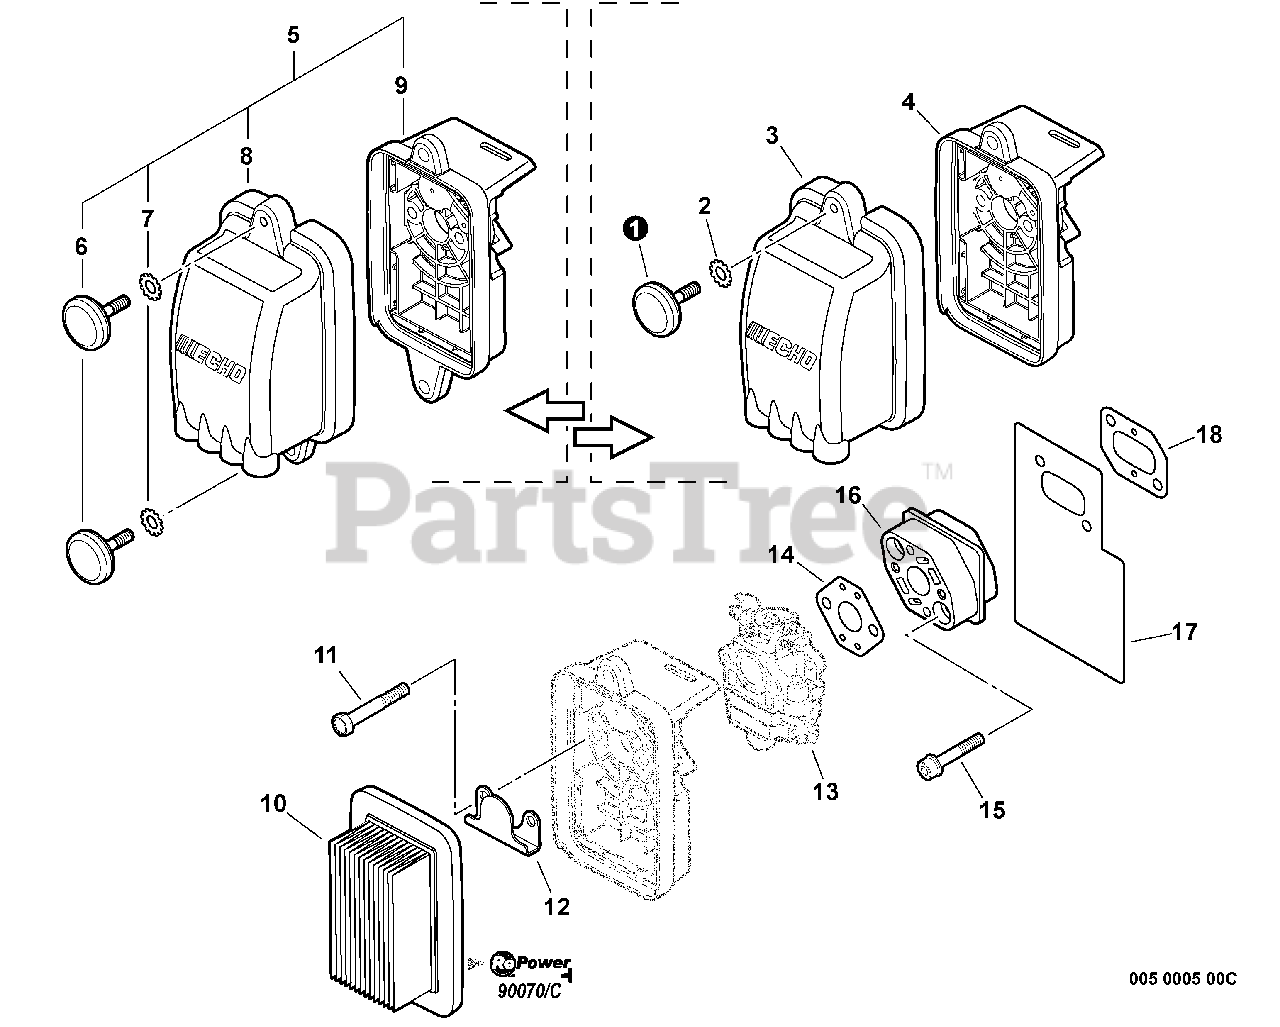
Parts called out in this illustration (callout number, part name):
1	THUMBSCREW
2	LOCKWASHER
3	COVER, AIR FILTER
4	AIR FILTER CASE ASSY
5	AIR CLEANER KIT
6	THUMBSCREW
7	LOCKWASHER
8	COVER, AIR FILTER
9	AIR FILTER CASE ASSY
10	FILTER, AIR
11	SCREW - 5X55
12	PLATE, PREVENT
13	CARBURETOR
14	GASKET, INTAKE
15	SCREW - 5X25
16	INSULATOR, INTAKE
17	SHIELD, INTAKE
18	GASKET, INTAKE
19	RePower TUNE-UP KIT
